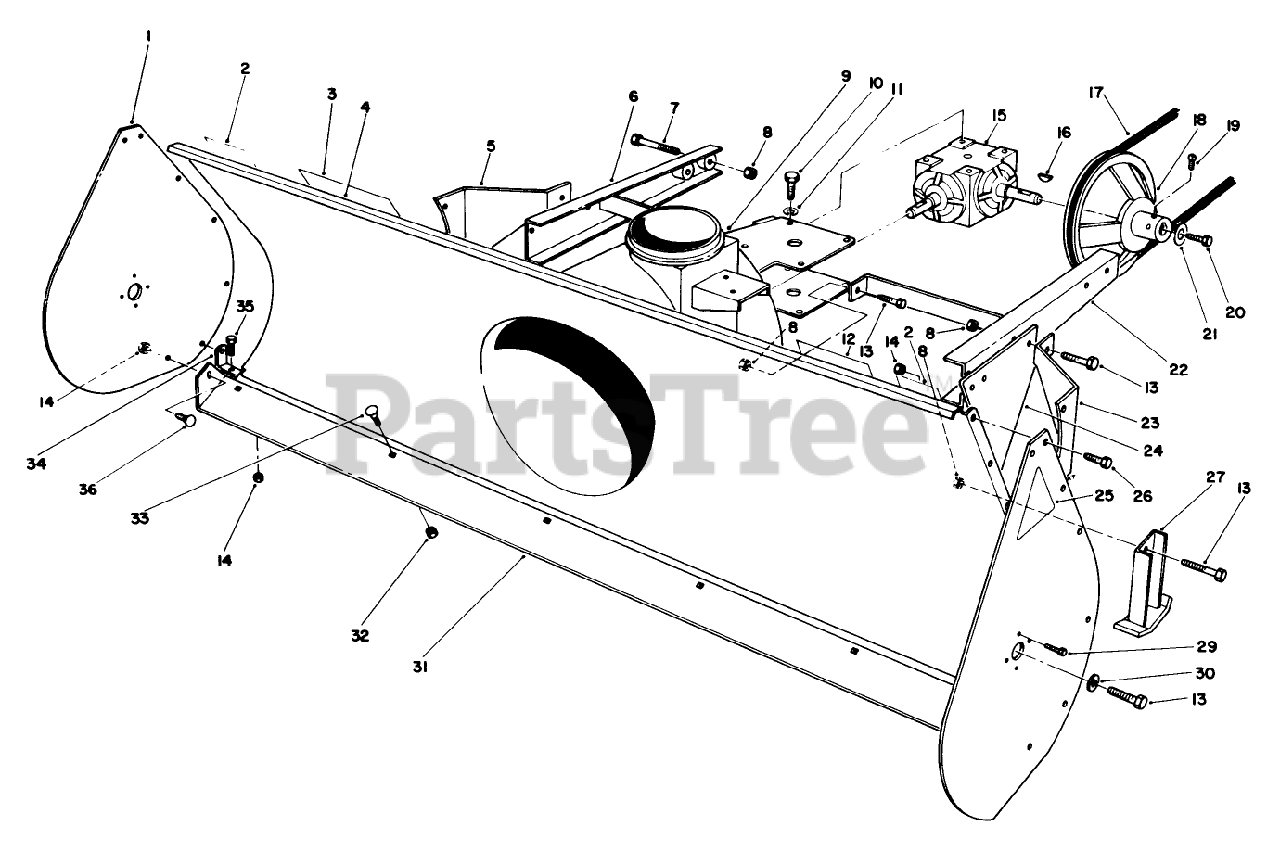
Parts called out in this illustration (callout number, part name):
1	Plate-Side
2	DECAL-WARNING, AUGER
3	Decal-Warning
4	HOUSING WA R
5	RH EXTENSION PLT R
6	RH EXT BAR WA R
7	SCREW-HH
8	NUT-LOCK, NI
9	CHUTE RING
10	SCREW-HH
11	WASHER-LOCK, INTERNAL
12	Decal-Rear Weight
13	SCREW-HH
14	NUT-LOCK, NI
15	GEARBOX
16	KEY-WOODRUFF
17	V-BELT
18	DRIVE PULLEY
19	SCREW-SET, SQH
20	BOLT 60183
21	WASHER-FLAT
22	LH EXT BAR WA R
23	LH EXTENSION PLT R
24	SKID MTG PLT R
25	AUGER SIDE PLT DECAL
26	SCREW-HH
27	SKID WA R
29	SCREW-HH
30	WASHER
31	Blade-Scraper
32	NUT-LOCK, NI
33	SCREW-CARR
34	BLADE SUPPORT BRKT R
35	SCREW-HH
